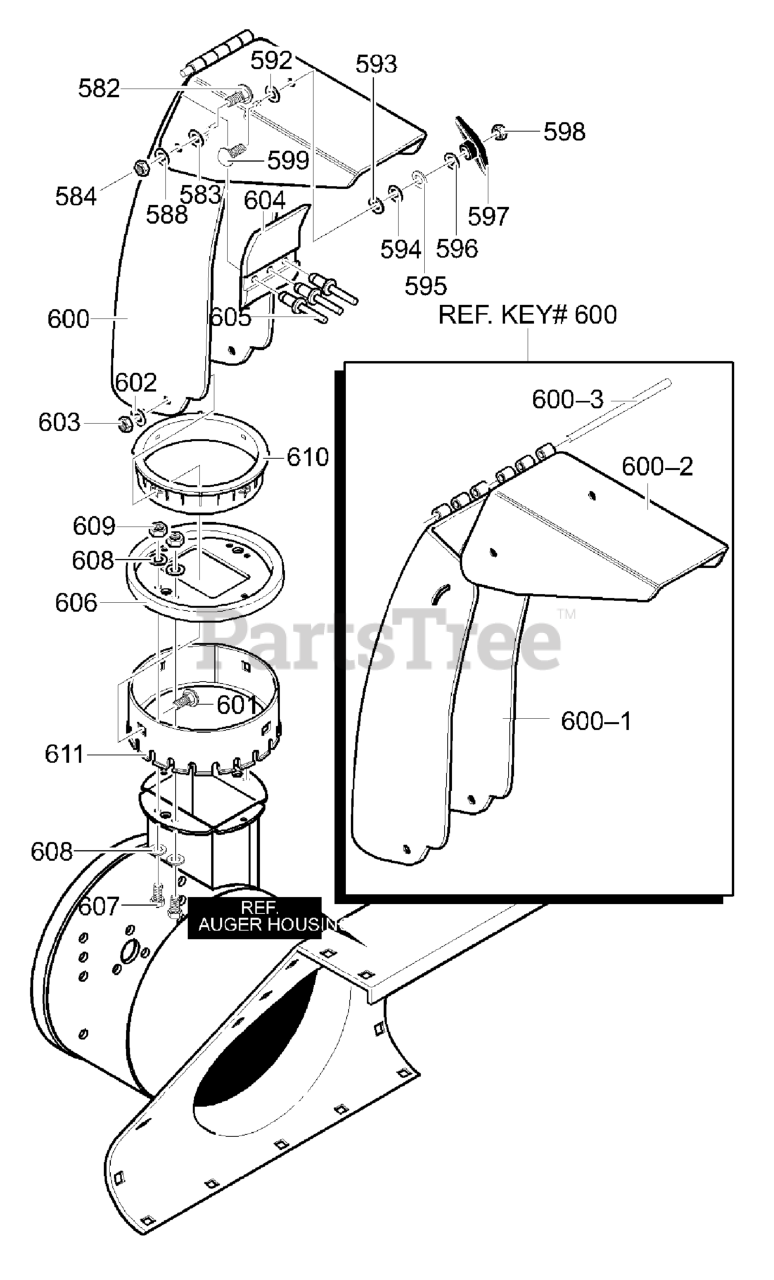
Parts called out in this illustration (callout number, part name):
582	BOLT
583	WASHER, PLASTIC
584	NUT
588	WASHER, PLASTIC
592	WASHER, PLASTIC
593	WASHER, PLASTIC
594	WASHER, FLAT
595	WASHER
596	WASHER, FLAT
597	T-KNOB
598	NUT
599	BOLT, CARRIAGE
600	CHUTE, ASSEMBLY WITH GUARD
600-1	CHUTE, LOWER
600-2	UPPER, CHUTE
600-3	PIN, HINGE
601	BOLT, 5/16-18X1.00
602	FLATWASHER
603	NUT, 5/16-18
606	COLLAR, CHUTE
607	SCREW, 1/4-20X .75
608	FLATWASHER
609	NUT, 1/4-20 HEX NYLOCK
610	RETAINER, RING INNER
611	RETAINER, RING OUTER
